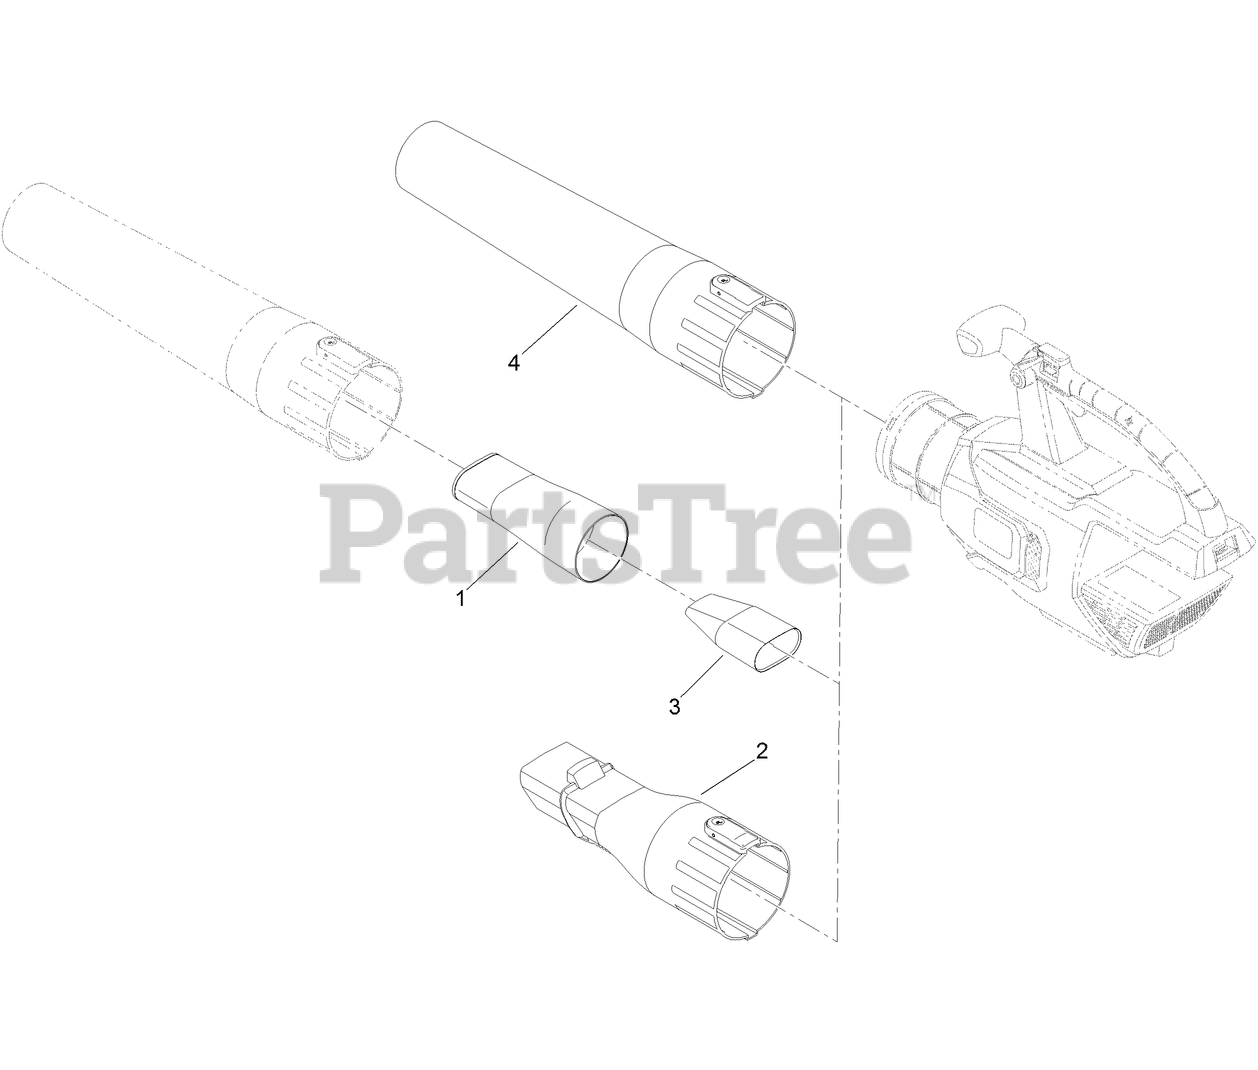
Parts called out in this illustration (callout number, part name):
1	Adapter-Oscillator, MPH
2	ADAPTER-CLEANER, GUTTER
3	Adapter-Insert, MPH
4	TUBE-BLOWER
